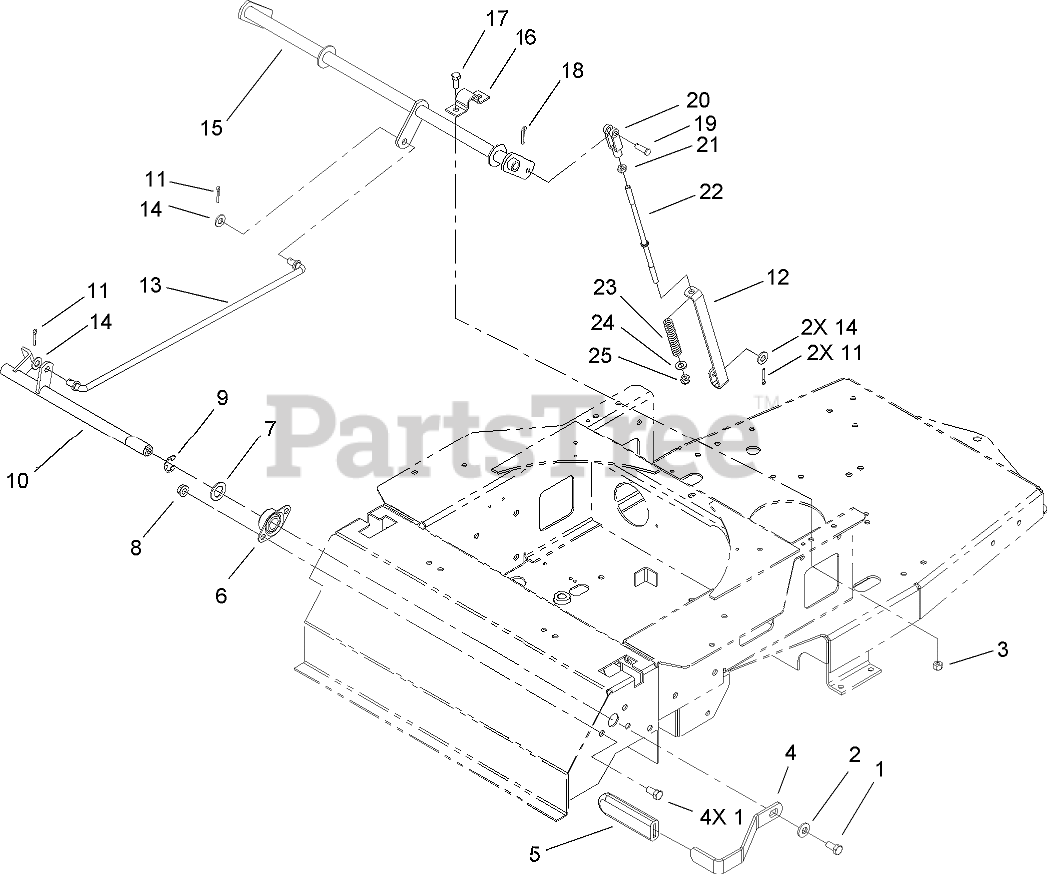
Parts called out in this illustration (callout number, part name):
1	SCREW-HH
2	WASHER-BELLEVILLE
3	NUT-LOCK, NI
4	HANDLE-BRAKE, PARK
5	GRIP-LEVER
6	BEARING-FLANGE, SIDE
7	WASHER
8	NUT-HHF, WHIZ
9	E-RING
10	BRAKE SHAFT ASM
11	PIN-COTTER
12	BRACKET-SPRING, BRAKE
13	ROD-BRAKE, UPPER
14	WASHER-FLAT
15	SHAFT-BRAKE
16	CLAMP-PIVOT, HOC
17	SCREW-HH
18	PIN-COTTER
19	PIN-CLEVIS
20	YOKE-ADJUSTABLE
21	NUT-HEX
22	ROD-BRAKE, UPPER
23	SPRING
24	WASHER-PLAIN
25	NUT-LOCK
